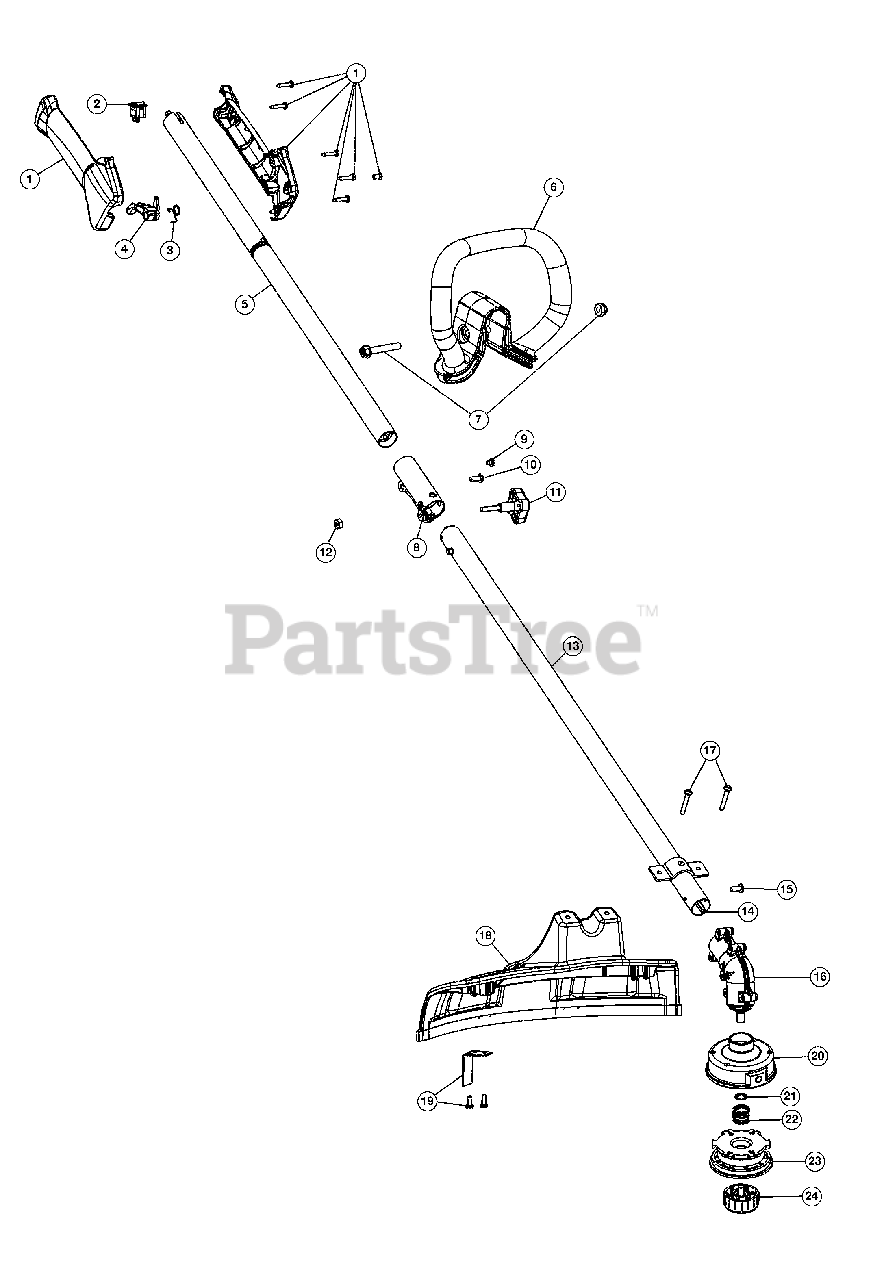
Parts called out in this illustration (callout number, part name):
1	Throttle Housing Assembly (Incl. 2-4)
3	Throttle Trigger
4	Throttle Trigger Spring
5	Upper Drive Shaft Housing Assembly
6	D-Handle (Incl. 7)
7	D-Handle Bolt
8	Split Boom Coupler (Incl. 9-12)
11	Adjustment Knob (Incl. 12)
12	Knob Retaining Nut
13	Lower Drive Shaft Housing Assembly
14	Lower Flexible Drive Shaft
15	Anti-Rotation Screw
16	Gear Box Assembly (Incl. 15 & 20-24)
17	Shield Mounting Screws
18	Shield Assembly (Incl. 17 & 19)
19	Blade Assembly
20	Outer Spool Assembly
23	Inner Reel
24	Bump Knob Assembly
